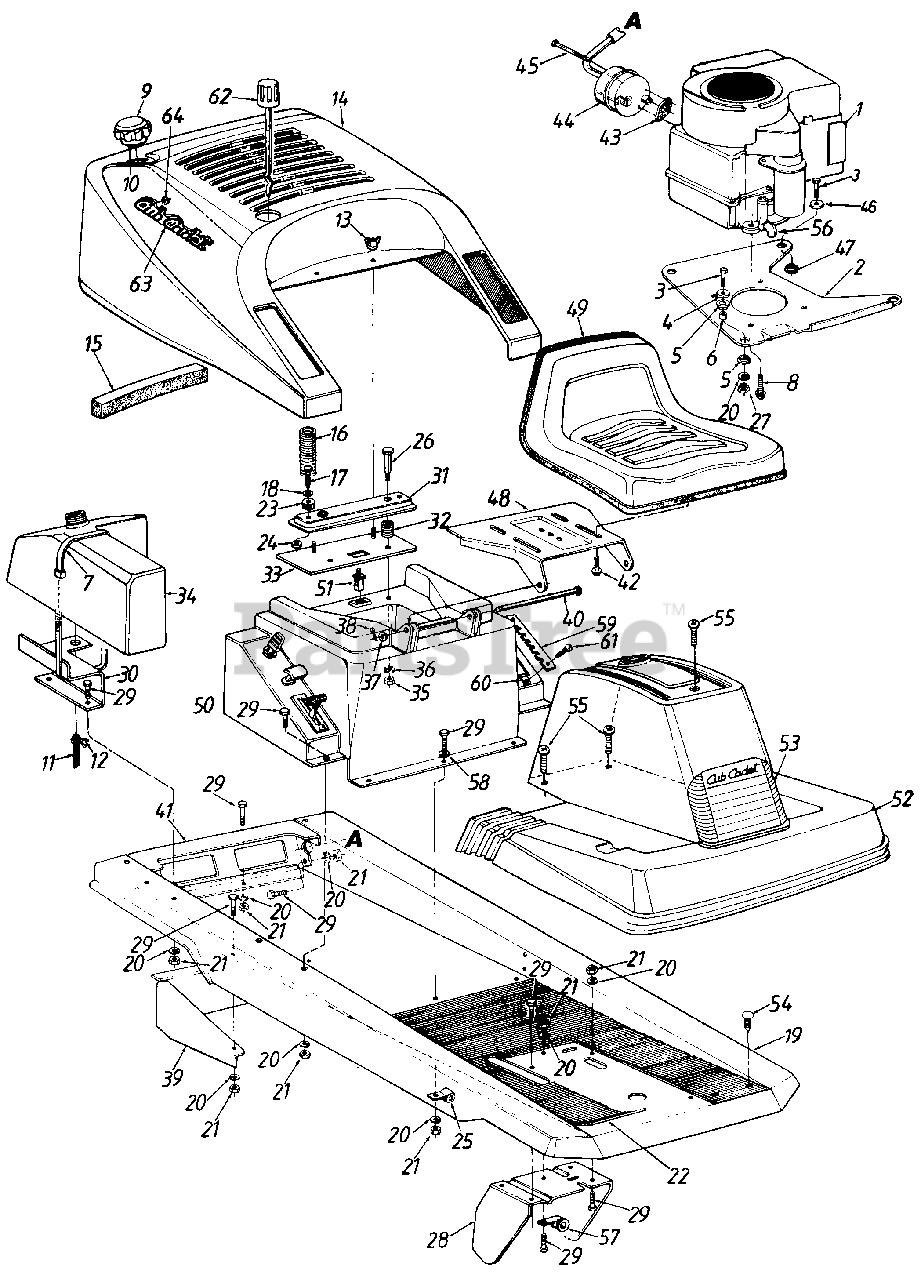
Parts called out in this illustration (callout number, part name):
1	Engine
4	Fl-Wash. .33" I.D. x 1.125" O.D.
5	Engine Mounting Grommet
6	Spacer .315" I.D. x .5" O.D.
7	Cable Tie 30.6" Lg.
8	Hex Wash. Hd. Self-Tap Scr. 3/8-16 x 1.25" Lg.
11	Gas Line--15" Lg.
12	Hose Clamp
13	Wing Nut 1/4-20 Thd.
14	Rear Engine Cover
15	Foam Strip--2 Req'd.
16	Compression Spring
17	Hex Bolt 5/16-18 x 7/8" Lg. (Gr. 5)
18	Fl-Wash. .344" I.D. x .875"
21	Hex Nut 5/16-18 Thd
23	Elastemer Bushing
24	Hex Cent. L-Nut 5/16-18 Thd. (Gr. 5)
26	Shld. Bolt .5" Dia. x .84
27	Hex Nut 5/16-24 Thd.
28	Clutch Pedal Brkt. Ass'y.
29	Hex Bolt 5/16-18 x .75" Lg
35	Hex Nut 3/8-16 Thd
36	L-Wash. 3/8" 1 .D.
37	Fl-Wash. .469" 1 .D. x .88" O.D.
38	Cotter Pin 3/32" Dia. x 1.0" Lg.
43	Exhaust Gasket
45	Shld. Bolt 7/16" Dia. x 3-5/8"
46	Fl-Wash. .33" I.D. x 1.125" O.D.
47	Flange Washer .32" I.D. x .5"
50	Seat Support
51	Safety Switch (Seat)
52	Front Console
53	Headlight Lens
54	Ratchet Fastener .25" Dia. x .75" Lg.
55	Pan Hd. Tap Scr. #12 x .5" Lg.
56	90ø Elbow Male to Female
57	Cable Clip
58	Fl-Wash. .34" I.D. x .68" O.D.
59	Lift Reinforcement
60	Speed Nut #10-24 Thd.
61	Fl-Counter Sunk Scr. #10-24 x 1.5" Lg.
62	Oil Fill Extension
63	Logo
64	Push Nut
